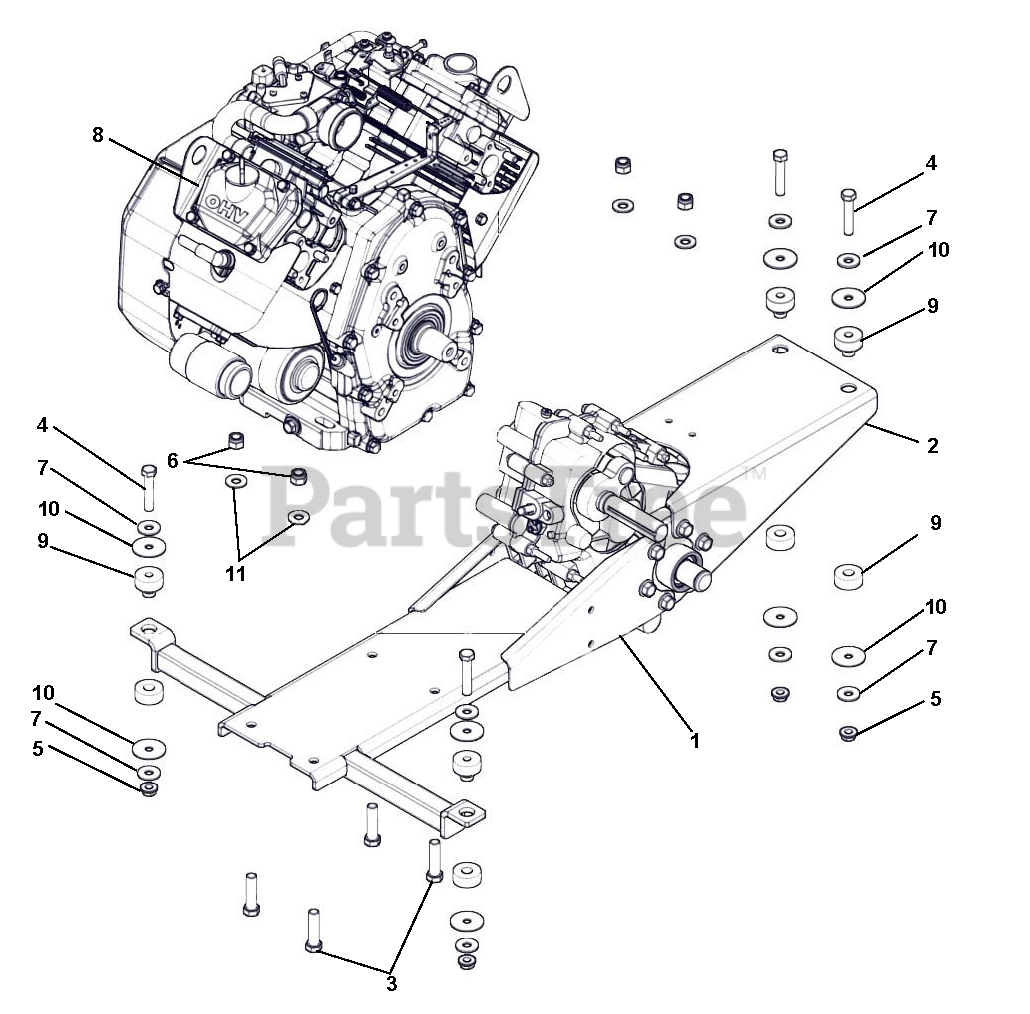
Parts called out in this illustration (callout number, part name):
1	ENGINE MOUNT WELDMENT
2	TRANS MNT SUPPORT BRACKET ST
3	@BLT-HEX .44-14X1.75 GR5 YWZC
4	@BLT-HEX .38-16X2.00 GR5 YWZC
5	@NUT-LK-TOP-FLG .38-16 YWZC
6	NUT-LK-TOP .437-14 GR C PL
7	@WSHR-FL-STL.438X1.00X.083 YWZ
8	ENGINE, SUBARU EH65
9	MOUNT MOTOR H SYTLE
10	WSHR-FL-STL .402X2.00X.055 YWZ
11	@WSHR-FL-STL.531X1.06X.095YWZC
